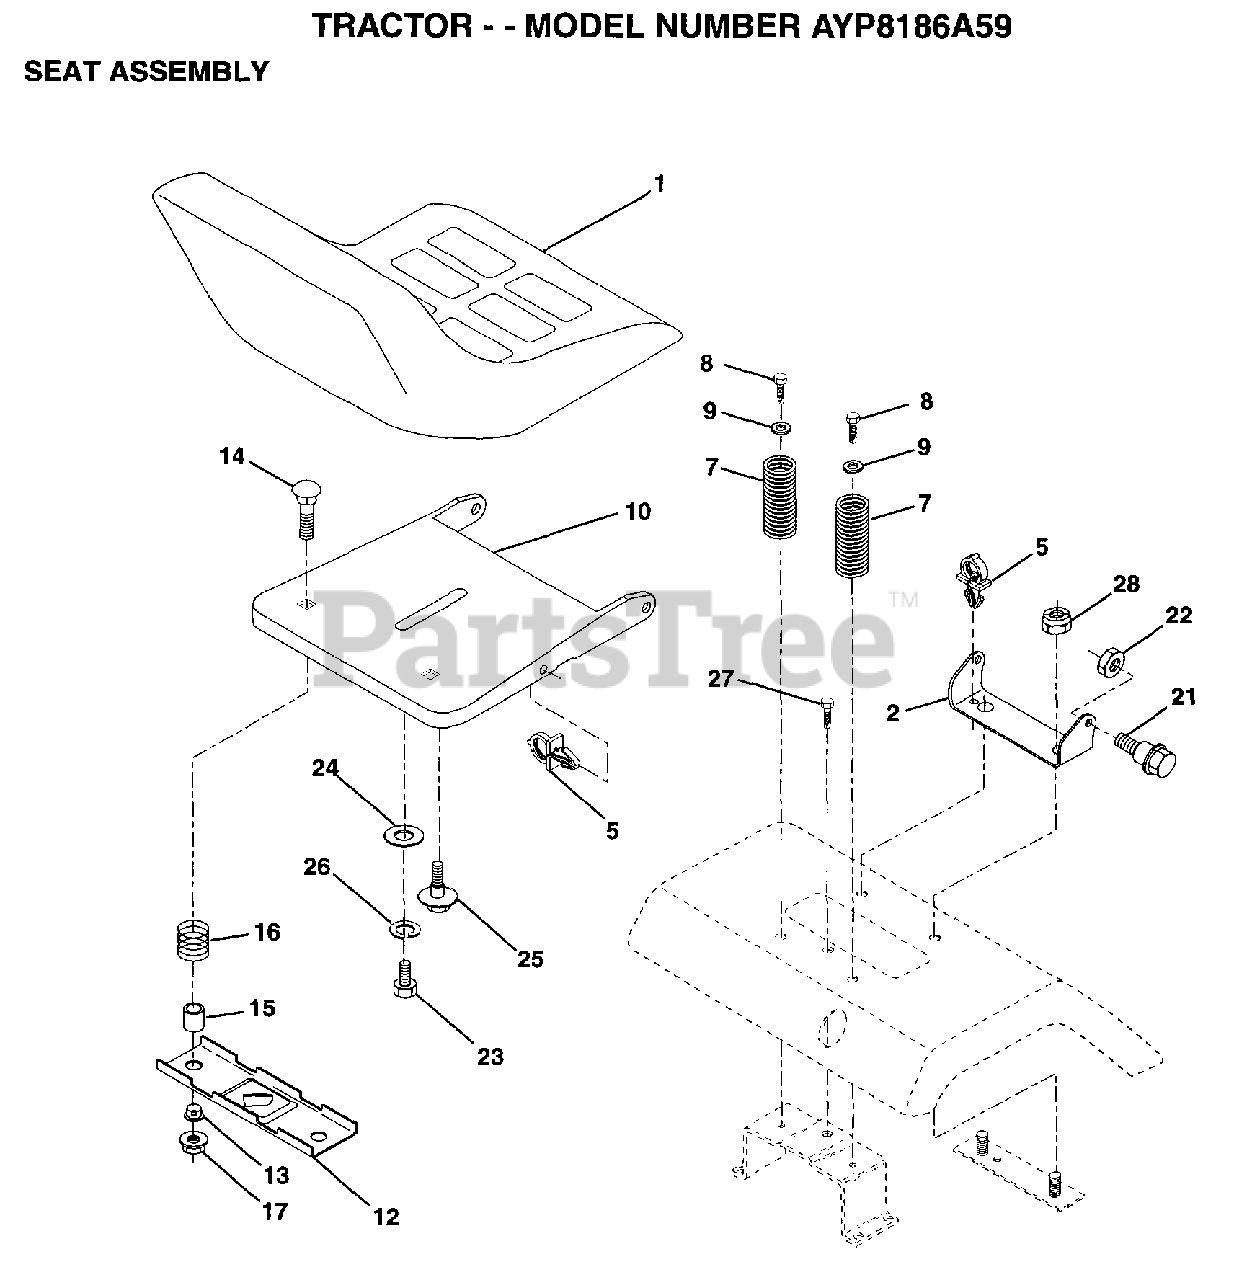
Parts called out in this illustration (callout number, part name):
2	BRACKET PVT SEAT
5	CLIP.PUSH-IN.HING
7	SPRING COMPRESSIO
8	SCREW LT
9	WASHER
12	BRKT SWITCH
13	BUSHING
15	SPACER SPLIT
16	SPRING COMPRESSED
21	BOLT.SHLD.5/16-18
23	BOLT
24	WASHER
25	"BOLT,SHOULDER"
26	LOCKWASHER
27	SCREW LT
